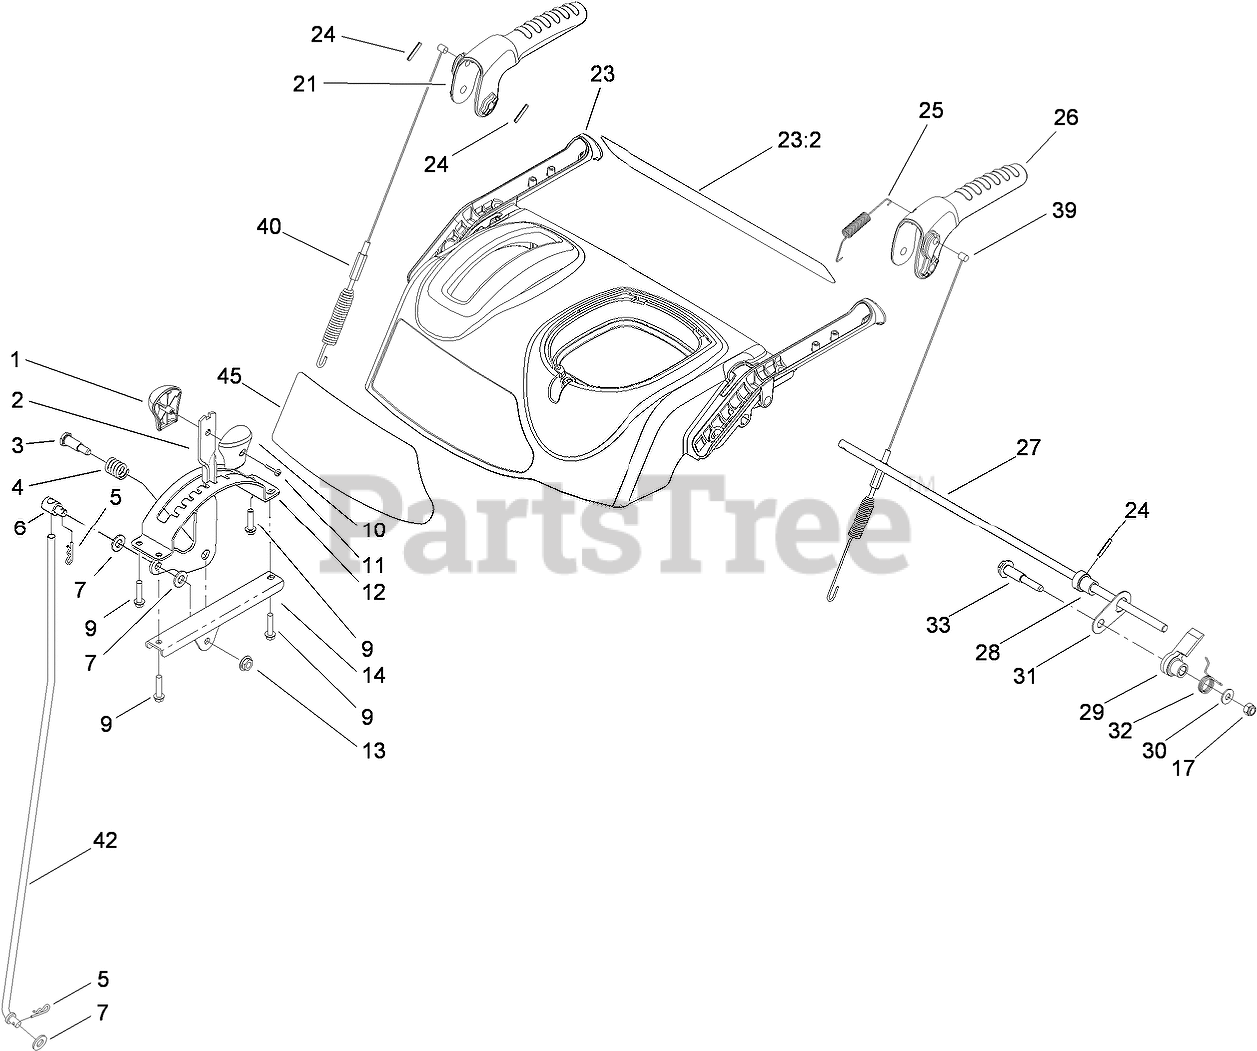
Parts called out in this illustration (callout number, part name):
1	KNOB-SHIFT, RH
2	SELECTOR-SPEED
3	SCREW-SHOULDER
4	SPRING-COMPRESSION
5	PIN-COTTER
6	TRUNNION-ROD
7	WASHER-FLAT
9	SCREW-PLASTITE
10	KNOB-SHIFT, LH
11	SCREW-PPH
12	GUIDE-SELECTOR, SPEED
13	NUT-HF
14	MOUNT-SELECTOR, SPEED
17	NUT-LOCK, NI
21	LEVER-AUGER
23	CONTROL PANEL ASM
23:2	DECAL-PANEL, CONTROL
24	PIN-SPRING
25	SPRING-TENSION
26	LEVER-TRACTION
27	ROD-LOCKOUT
28	CAM-LOCKOUT
29	LATCH-LOCKOUT
30	WASHER-FLAT
31	LINK-LOCKOUT
32	SPRING-TORSION
33	SCREW-SHOULDER
39	CABLE-TRACTION
40	CABLE-AUGER
42	ROD-SHIFT
